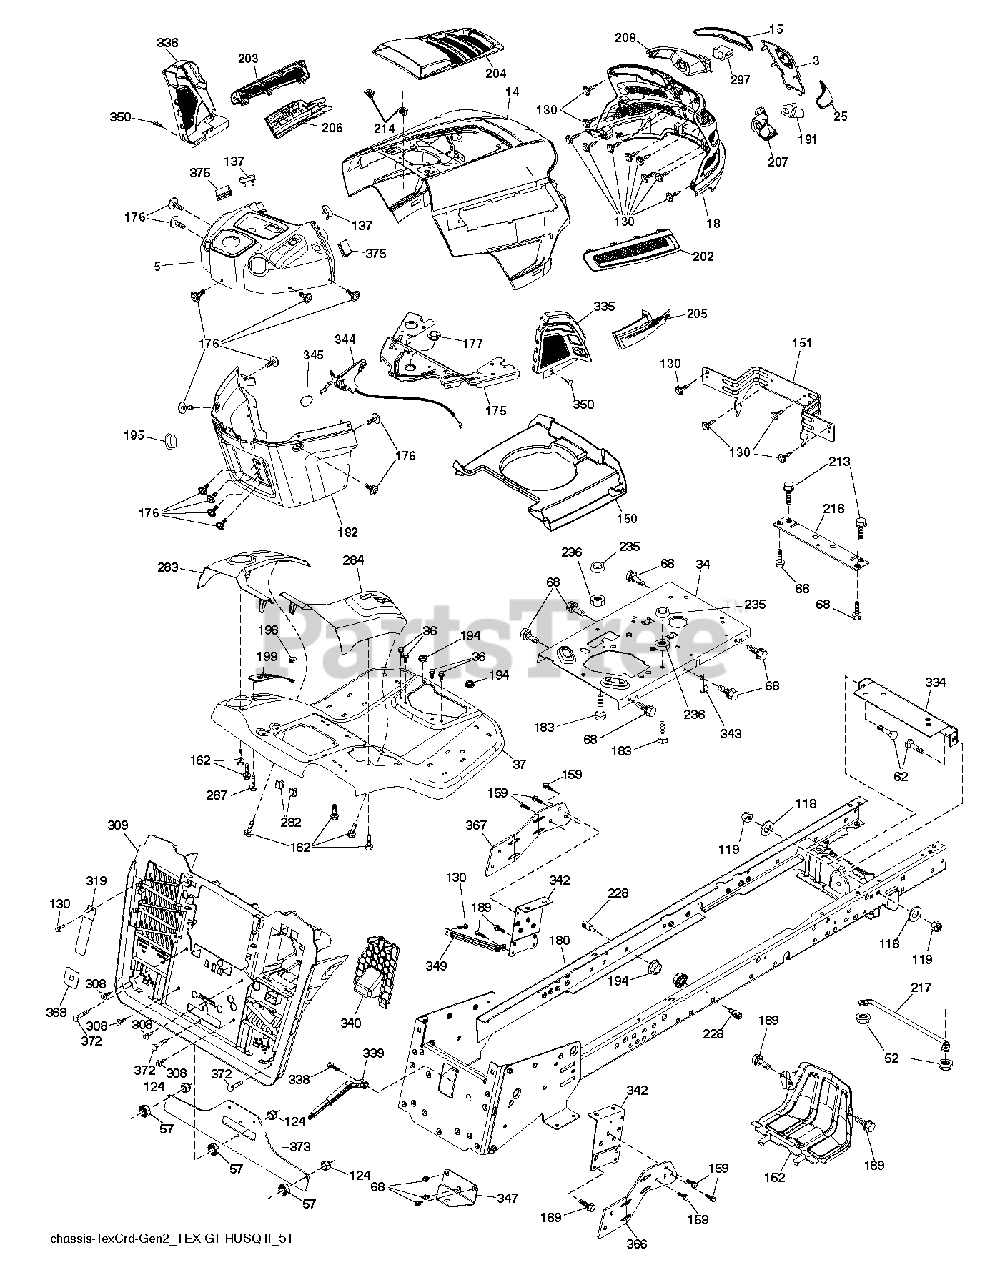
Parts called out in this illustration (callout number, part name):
3	APPLIQUE.SUBASM.GT.HUSQ.II
5	UPPER.GT2.SVC.MINDING.PTO.H.
14	HOOD.ASM.HUSQVARNA.GT.TEX.ORAN
15	LENS.HEADLIGHT.LH.GTII.2011
18	GRILLE.SUBSTRATE.2011.
25	LENS.HEADLIGHT.RH.GTII.2011
34	PLATE.ENGINE.10GA.CRD.GENII
36	SCREW 5/16"
37	FENDER.TEX.SRD.CRD.BASE
52	LOCKNUT
57	NUT
62	BOLT D
68	SCREW LT
118	WASHER
124	LOCKNUT.NYLOC.1/4-20
130	SCREW.#10 X 0.750.BOS
137	BUMPER DASH
150	AIR.DUCT.GTV.BLACK
151	BRACKET.PIVOT.HOOD.GT.HUSQ.II
152	SHIELD.BROWNING.PNT.GT.V2
159	SCREW, 3/8-16X3/4
162	SCREW.HI-LO.CONSOLE
175	PLATE.CROSSMEMBER.HUSQ
176	SCREW.#10-24X5/8.RN.QU
177	BUSHING STEERING
180	WELDMENT.CHASSIS.TEX.CRD.GEN.2
182	DASH DASH LOWER
183	BOLT.5/16-18X1-1/4 FULL THD
189	SCREW
191	INSERT.REFLECTIVE.RH.HUSQ.GTII
194	NUT LOCK HEX FLANGE 5/16-18
195	PLUG.HOLE.DASH.LOWER.12V.BLK
198	INDICATOR.DECK.LIFT.RED
199	PLATE DECK LIFT
202	VENT.SIDE.RH.GT.HUSQ.II.
203	VENT.SIDE.LH.GT.HUSQ.II.498
204	VENT.TOP.HUSQ.GT2
205	SIDE.TRIM.RH.GT.HUSQ.II
206	SIDE.TRIM.LH.GT.HUSQ.II.GRAY
207	BEZEL LIGHT.RH.GT.II.MYLAR
208	BEZEL LIGHT.LH.GT.II.MYLAR
213	BOLT
214	CLIP.RETAINER.TINNER.
217	ROD.PIVOT.HOOD
218	X-PIECE.HOOD.STOP.NON/
228	STUD.FASTNER.W/ANTI-ROTATE
235	SPACER FENDER
236	NUT.CENTERLOCK.5/16-
282	CLIP.RETAINER.CONSOLE.LT.HUSQ
283	CONSOLE.DECKLIFT.CRDII.498
284	CONSOLE.PEDAL.HYDRO
287	SCREW 1/4X20
297	INSERT.REFLECTIVE.LH.HUSQ.GTII
308	BOLT, 5/16-18 X 1 3/4
309	BACKPLATE.ASM.TEX.CRD.GEN2.1
319	LEVER.BAG.CRDII.ANTIROTATION
334	BRACKET.ENGINE
335	COVER.LOWER.DASH.RH.BLACK
336	COVER-LH.LOWER.DASH.GT2.BLACK
338	BOLT BOLT SHOULDER
339	LEVER LEVER BAGGER
340	BATTERY.DOOR.TEX.CRD.GEN.2,1
342	SUPPORT.PNT.FENDER.CRD.TEX
343	CLIP CLIP
344	CONTROL.EZ.MULCH.TEX/CRD
345	RP KNOB.OVAL.TAPERED.3/8-16BLK
347	HITCH HITCH TOW TEX CRD GEN 2
349	BRACKET.SUPPORT.LRVB/CRD
350	CLIP.X-MAS.TREE
366	BRACKET.RH.FRONT.BAGGER.BLACK
367	BRACKET.LH.FRONT.BAGGER.BLACK
368	FULL.LEVER.BAGGER.TEX.CRD
372	RHSNB, 1/4-20 X 1, GR5
373	REINFORCEMENT BACKPLATE. CRD B
375	BUMPER CLIP-ON. DASH 1"
